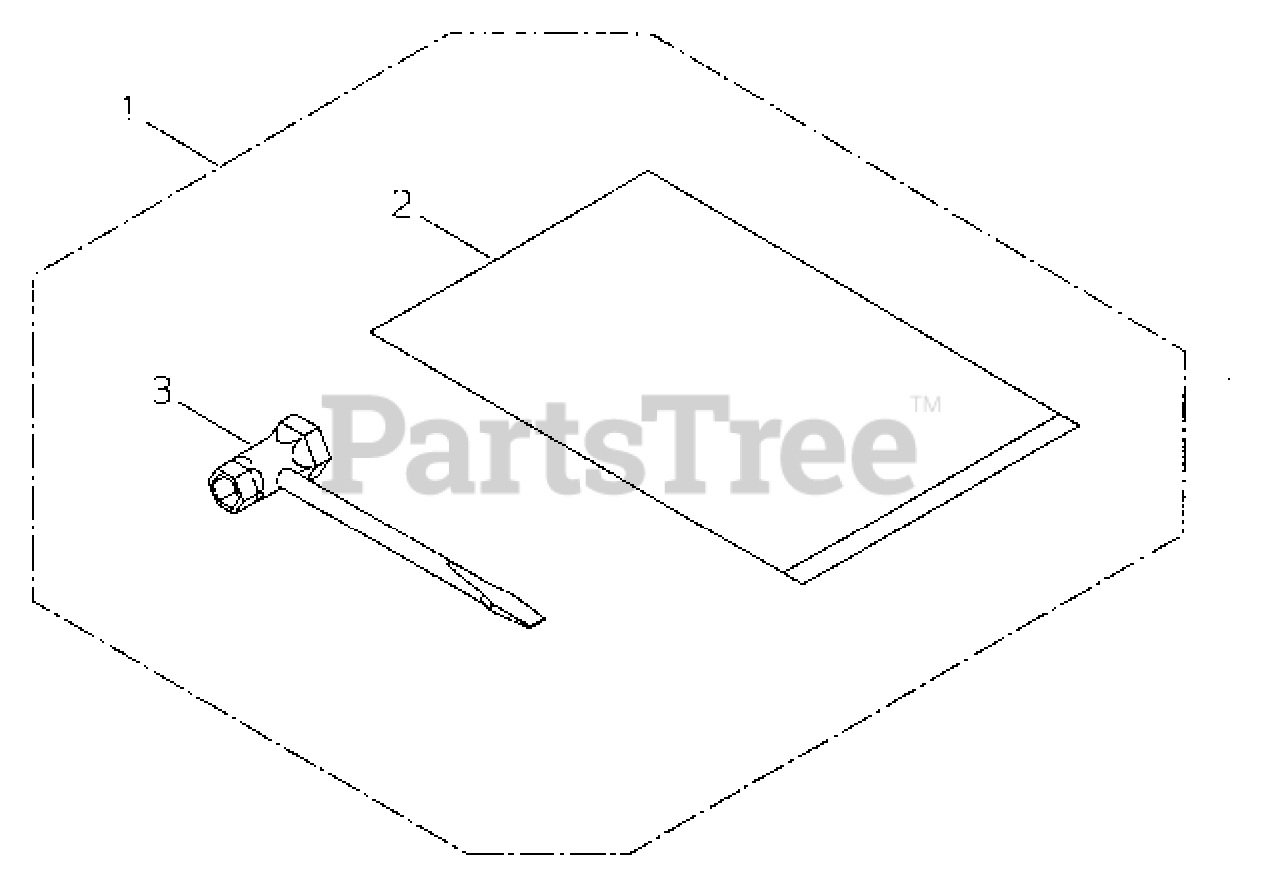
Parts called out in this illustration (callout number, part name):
1	SERVICE TOOL KIT
2	BAG, TOOL
3	T-WRENCH 13×19 MM
